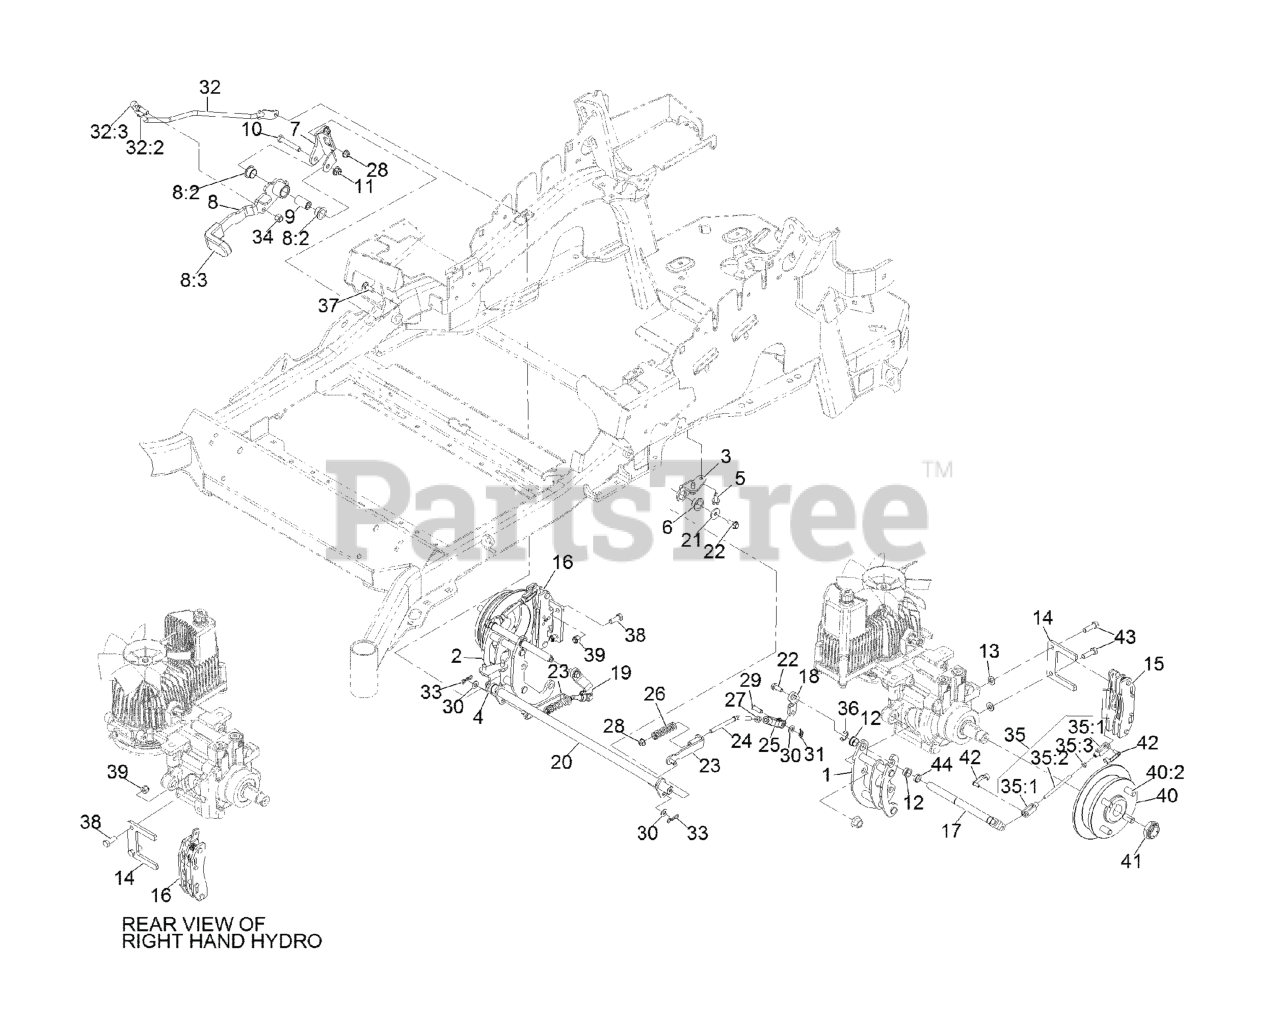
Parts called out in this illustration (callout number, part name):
1	MOUNT-BELLCRANK, LH
2	MOUNT-BELLCRANK, RH
3	MOUNT-PIVOT, LH
4	MOUNT-PIVOT, RH
5	Screw-HWH 5/16-18 X 3/4 Tf
6	BUSHING-FLANGE
7	BRACKET-MOUNT
8	BRAKE LEVER ASM W/ GRIP
8:2	BUSHING-FLANGE
8:3	GRIP-LEVER
9	HANDLE-PIVOT, BRAKE
10	SCREW-HH
11	NUT-HF, NI
12	BUSHING
13	WASHER-FLAT
14	PLATE-MOUNT, BRAKE
15	CALIPER-BRAKE
16	CALIPER-BRAKE, RH
17	BELLCRANK
18	ARM-INNER, LH
19	ARM-INNER, RH
20	SHAFT-CROSS
21	WASHER-FLAT
22	SCREW-HHF
23	BRACKET-L
24	LINKAGE-MID
25	YOKE-OFFSET
26	SPRING-COMPRESSION
27	NUT-JAM
28	NUT-HF, NI
29	PIN-CLEVIS
30	WASHER-PLAIN
31	PIN-COTTER, LOCKING
32	FRONT LINKAGE ASM
32:2	END-TIE ROD, RH
32:3	NUT-HJ
33	PIN-COTTER, LOCKING
34	NUT-LOCK
35	REAR LINKAGE ASM
35:3	NUT-JAM
37	BOLT-CARR
38	SCREW-HH
39	NUT-LOCK, NI
40	WHEEL HUB ASM
40:2	STUD-WHEEL
41	LOCKNUT
42	PIN-CLEVIS, SPRING
43	SCREW-LOCK, PATCH
